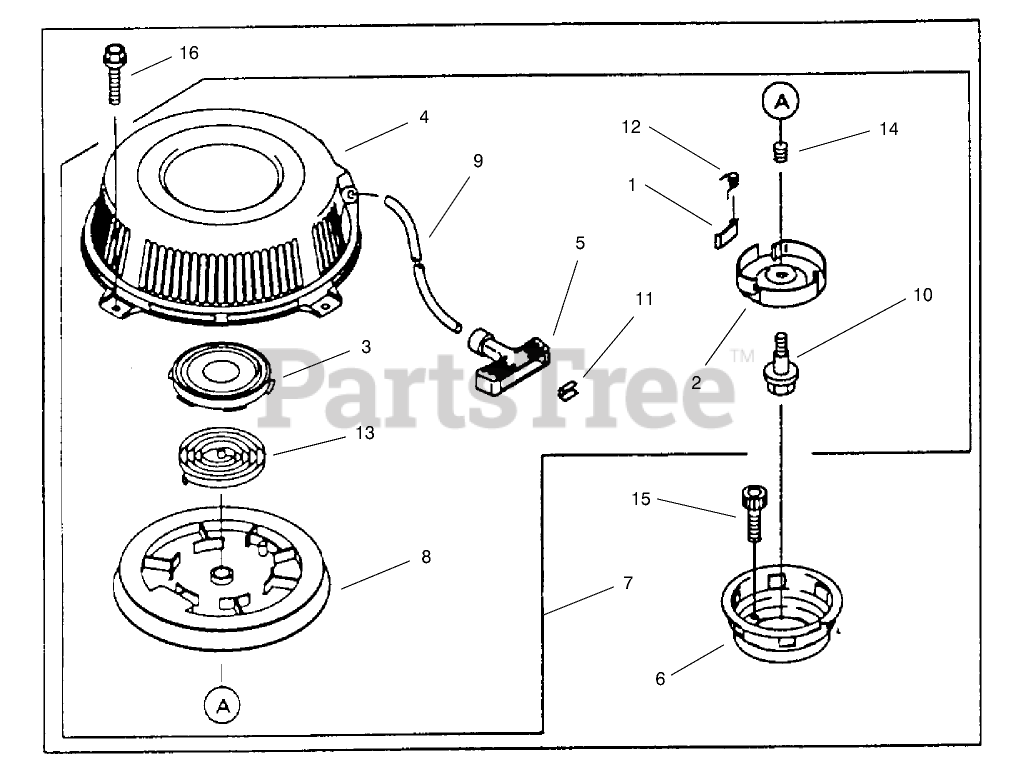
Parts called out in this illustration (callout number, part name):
1	Pawl
4	Case-Recoil Starter
5	Grip
6	Pulley-Starting
7	Starter-Recoil
10	Bolt
15	Bolt-Socket
16	BOLT-FLANGED (6X10)
